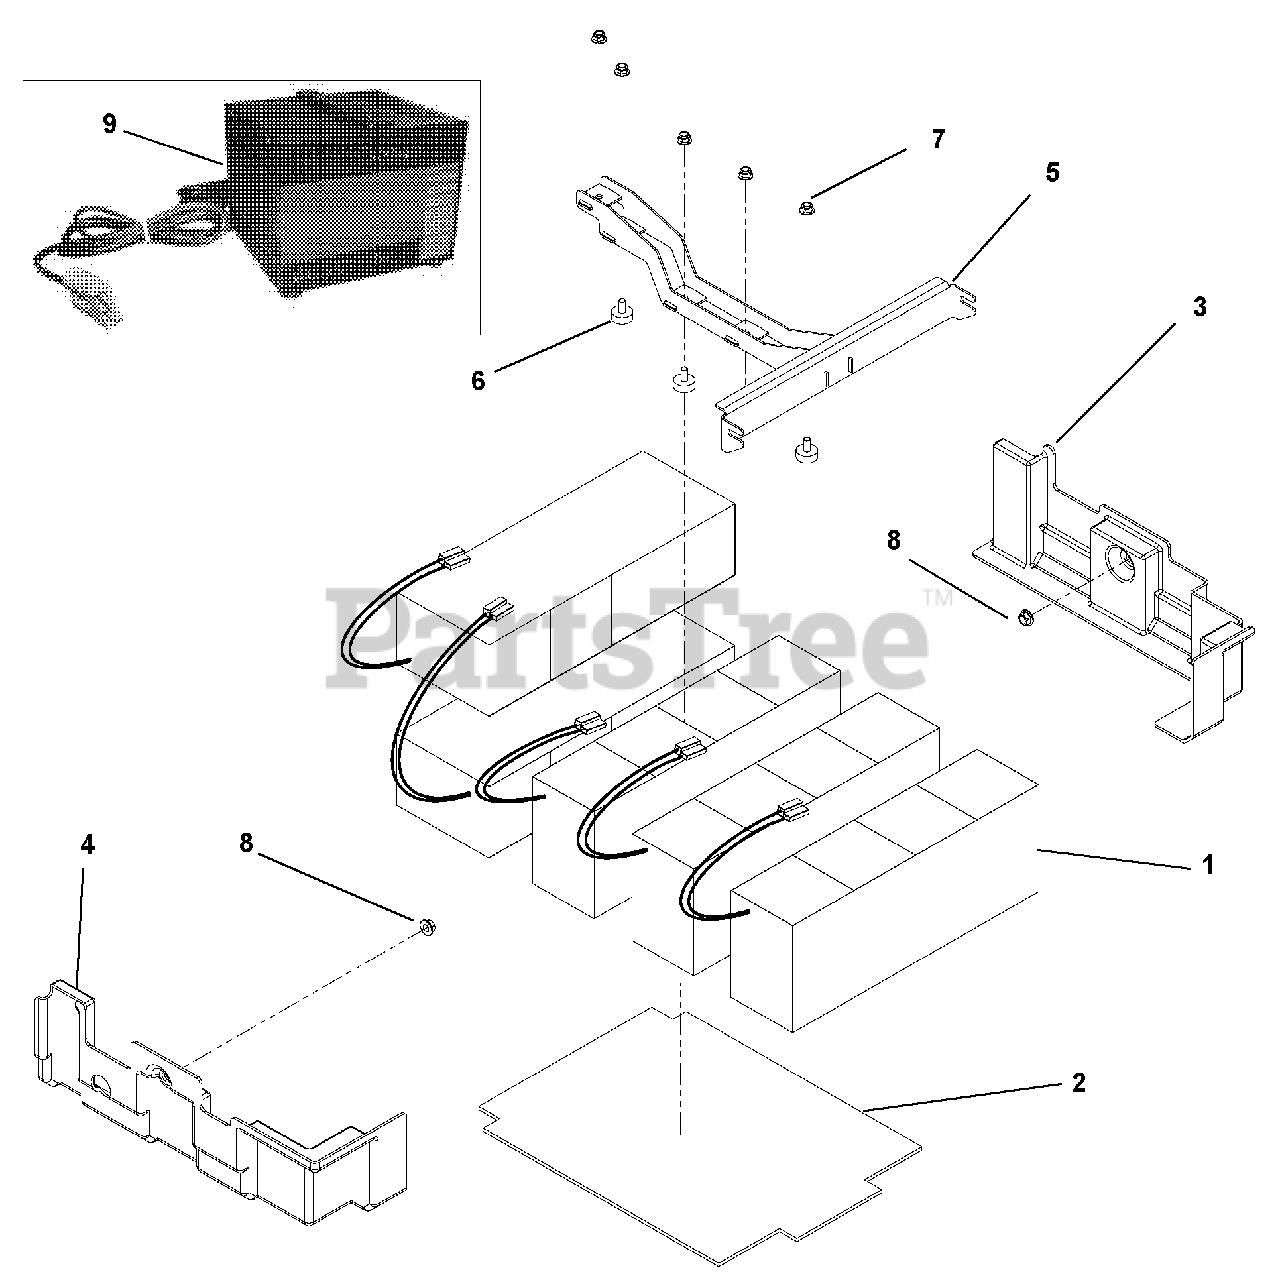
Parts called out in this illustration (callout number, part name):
1	BATTERY,SBS SUBPACK-48V 15AH
2	MAT, RUBBER BATTERY
3	SPACER, BATTERY, LH
4	SPACER, BATTERY, RH
5	CLAMP, BATTERY
6	BUMPER, RUBBER
7	@NUT-LK-NYL-FLG .31-18 YWZC
8	NUT-LK-CTR-FLG .38-16 YWZC
9	CHARGER, BATTERY 48V 5A HBR
